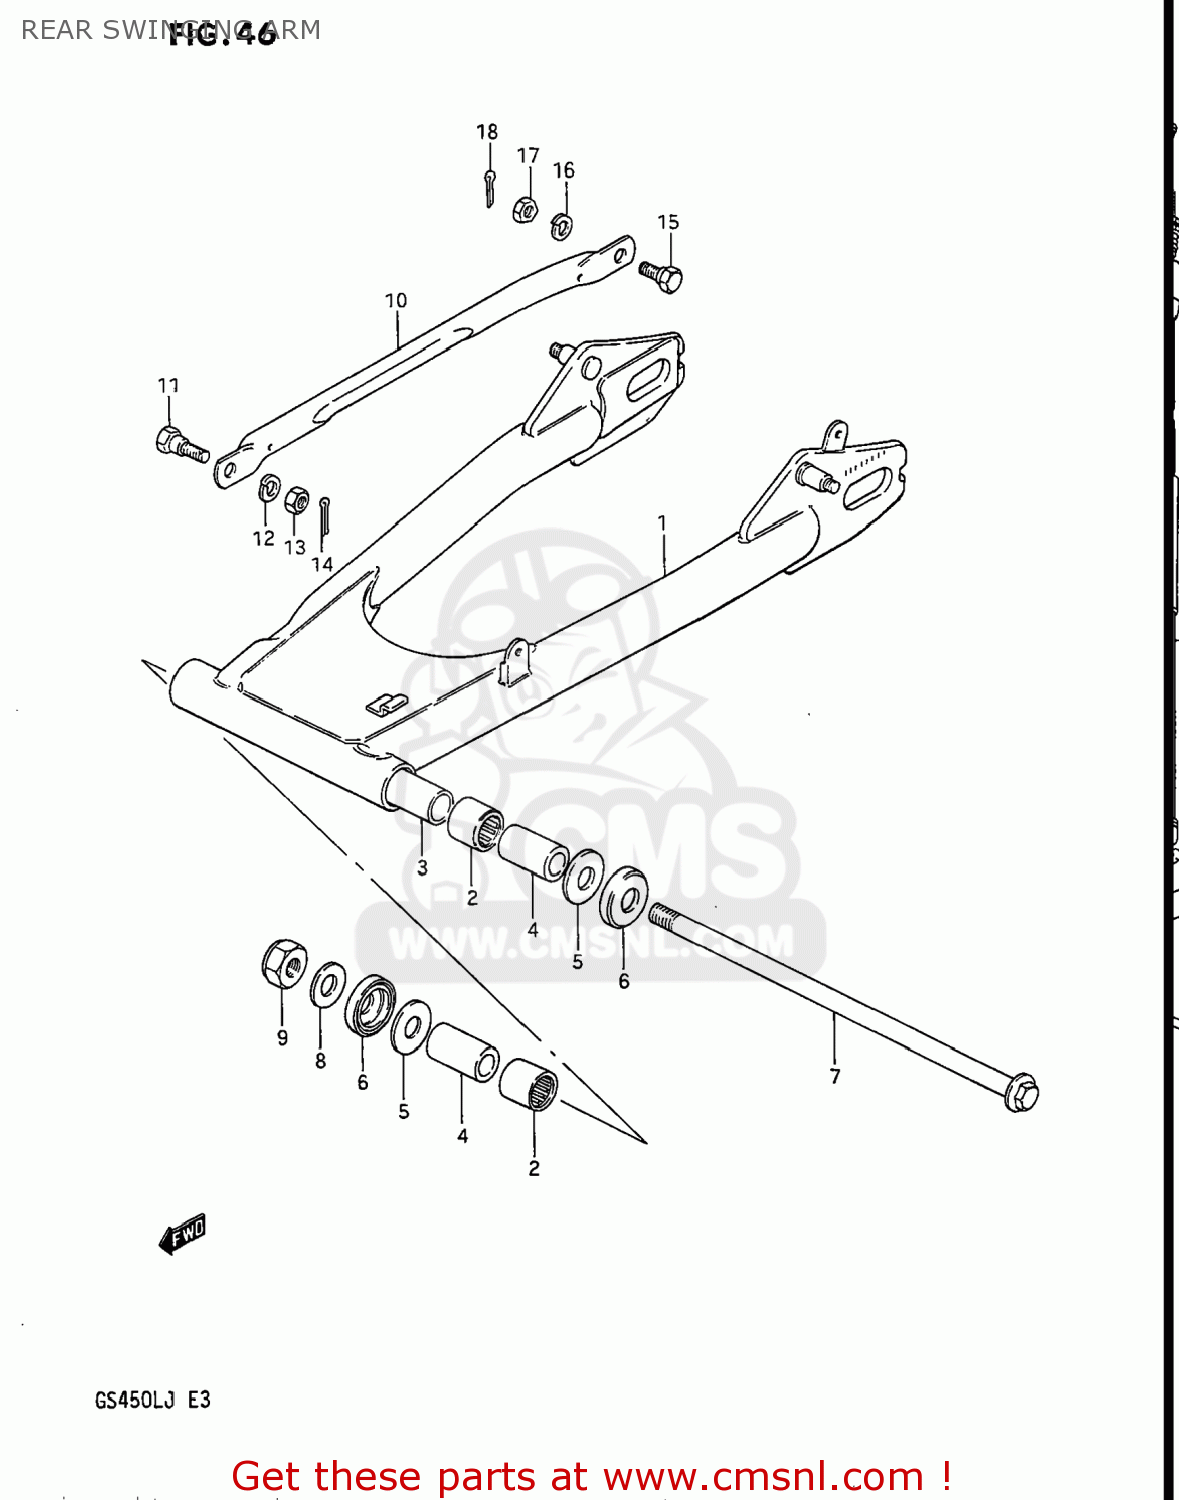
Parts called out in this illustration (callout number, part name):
1	ARM,REAR SWING
2	BEARING(22X29X30)
3	SPACER,SWINGINGARM CTR
4	SPACER,RR SWGARM PIVOT
5	WASHER(14.2X34X1)
6	CVR,RR SWGARM DUST SEAL(OD:40)
7	SHAFT,REAR SWING ARM
8	WASHER
9	NUT 14MM
10	LINK,REAR TORQUE
11	BOLT(10X24.5)
12	WASHER,LOCK,10
13	NUT
14	PIN 20X20
15	BOLT(10X31)
16	WASHER,LOCK,10
17	NUT
18	PIN 20X20
